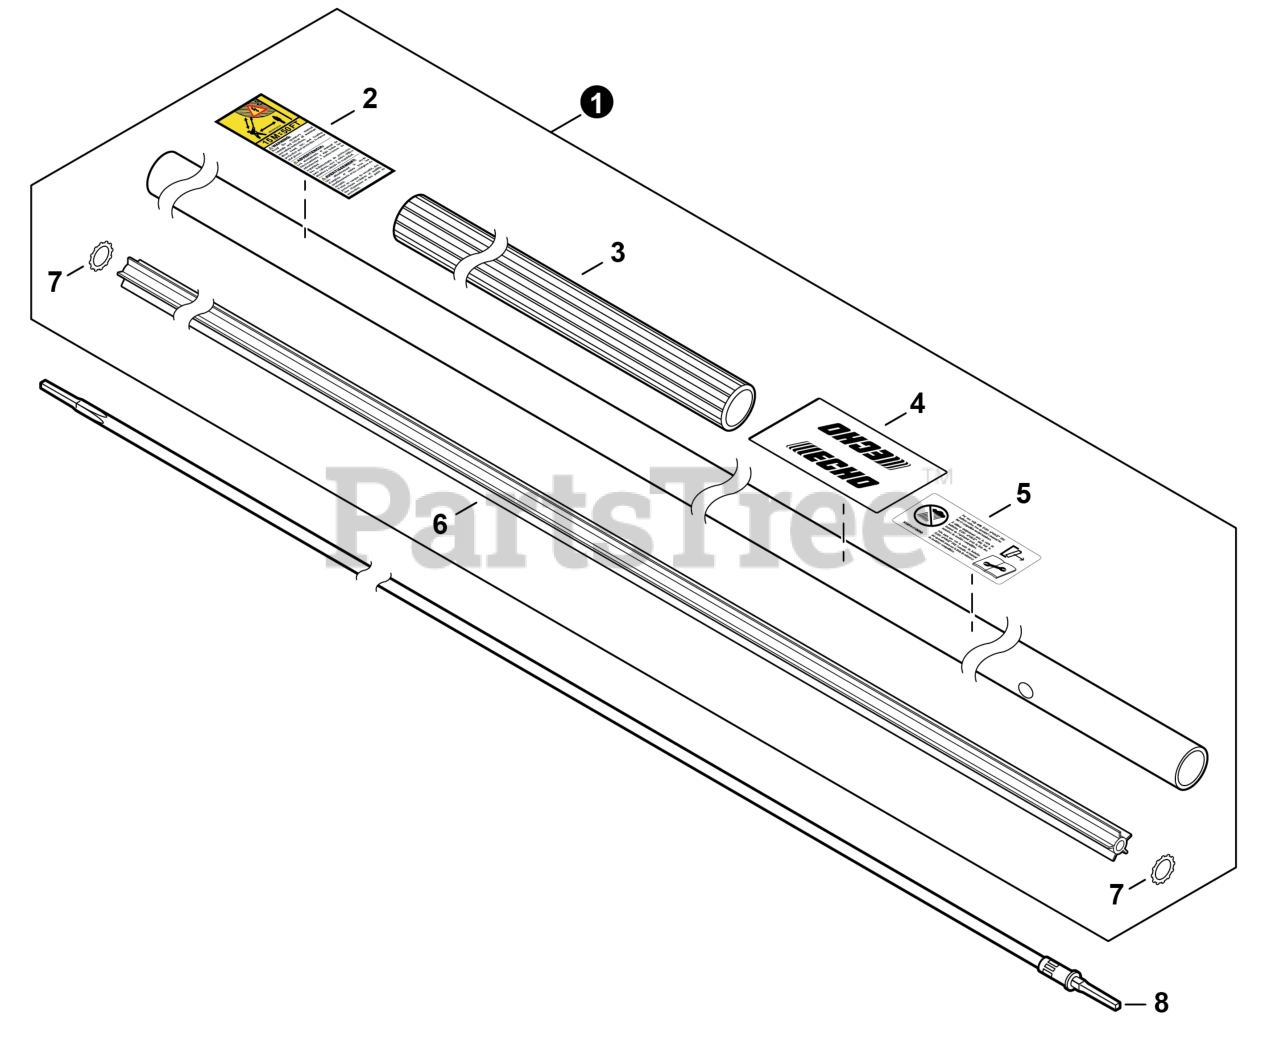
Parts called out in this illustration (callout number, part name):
1	MAIN PIPE ASSY
2	LABEL - CAUTION - ISO
3	GRIP, FRONT
4	LABEL - HANDLE LOCATION
5	LABEL - CAUTION - UL
6	LINER - FLEXIBLE
8	DRIVESHAFT - FLEXIBLE
